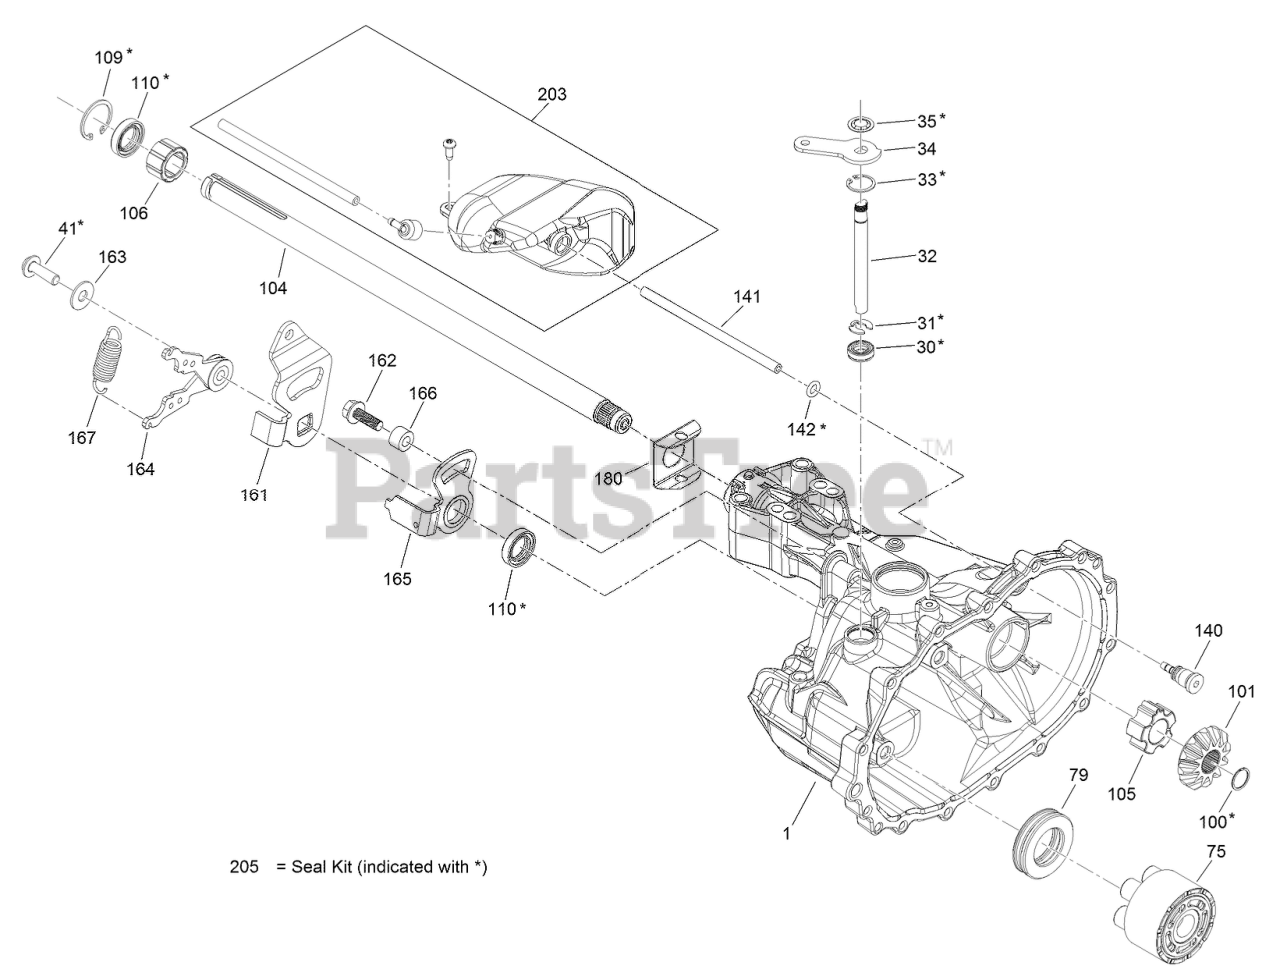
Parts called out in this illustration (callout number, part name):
1	MAIN HOUSING KIT
30	SEAL-LIP
31	RING-RETAINING, EXTERNAL
32	ROD-BYPASS, ACTUATOR
33	RING-RETAINING, INTERNAL
34	ARM-BYPASS
35	RING-RETAINING, EXTERNAL
75	CYLINDER BLOCK KIT
79	BEARING-THRUST
100	RING-RETAINING, SPIRAL
101	GEAR-BEVEL, 12T (SPLINE, ID)
104	SHAFT-AXLE, KEYED
105	BUSHING-INBOARD
106	BUSHING-OUTBOARD
109	RING-RETAINING, INTERNAL
110	SEAL-LIP
140	FITTING-SAE
142	O-RING
161	ARM-CONTROL, RETURN
162	SCREW-HF
163	WASHER
164	BI DIRECTIONAL RETURN KIT
165	ARM-NEUTRAL
166	BUSHING
167	SPRING-EXTENSION
180	SPRING CLIP-HOUSING THRUST
203	EXPANSION TANK KIT
205	SEAL KIT
